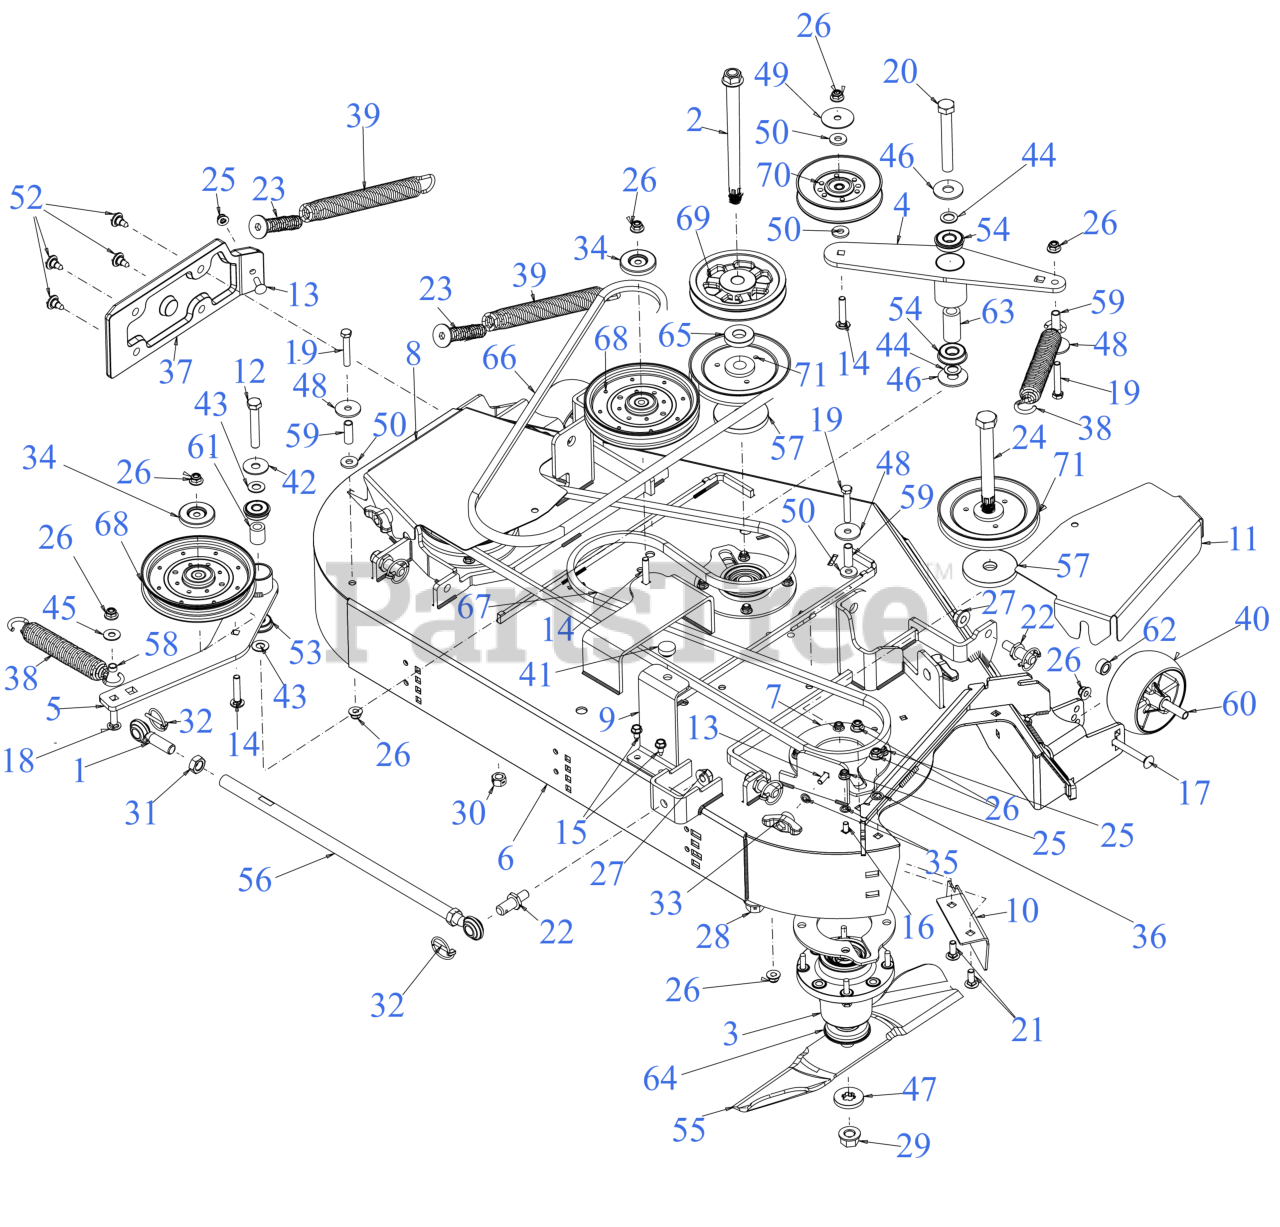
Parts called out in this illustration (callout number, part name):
1	MALE ROD END
2	SPINDLE SHAFT
3	SPINDLE ASSEMBLY
4	IDLER BRACKET
5	48" DECK IDLER BRACKET
6	48" FAB DECK
7	SPINDLE SUPPORT PLATE TOP & BOTTOM
8	BELT COVER (LH)
9	DECK STOP BRACKET
10	BAFFLE
11	48" BELT COVER (RH)
12	SCREW-HEX 1/2-13 x 3.00
13	CARRIAGE BOLT 5/16-18 x 1.00
14	CARRIAGE BOLT 3/8-16 x 2
15	SCREW 5/16-18 x .750
16	CARRIAGE BOLT 5/16-18 x .75
17	CARRIAGE BOLT 3/8-16 x 4.00 GR5
18	CARRIAGE BOLT 3/8-16 X1.25 GR5
19	SCREW 3/8-16 x 2.25 GR5
20	SCREW 5/8-18X4.5 GR5
21	CARRIAGE BOLT 3/8-16 x 1.00 GR5
23	SPRING INSERT SCREW
24	SPINDLE SHAFT
25	FLANGE LOCK NUT 5/16-18
29	FLANGE NUT - 5/8-18 GDE 8
30	HEX NUT CTR LK 1/2-13
31	HEX JAM NUT 5/8-18
32	LYNCH PIN .1875
33	WING KNOB 5/16-18
34	PULLEY CAP
35	PUSH NUT
36	PUSH NUT
37	DECK SKID PLATE (LH)
38	SPRING 1.25" DIA x 8.5" LONG
39	EXTENTION SPRING 1.20 x 11.35
40	DECK WHEEL
40	WHEELS-DELUXE 5"
41	RUBBER BUMPER 1.000 x .313
42	WASHER .51 x 1.5 x .07
43	FLAT WASHER .510 x .995
44	FLAT WASHER
45	WASHER-.395 x 1.0 x .62
46	FLAT WASHER 0.635xX1.755x0.110
47	FLAT WASHER - SPECIAL
48	FLAT WASHER .406X1.500X.105
49	HUB CAP WASHER .406 x 1.92 x .060
50	FLAT WASHER .406ID X1.0 OD
52	SHOULDER SCREW .43X.29X5/16-18 TT
53	ROLLER BEARING .5X1.37X.44
54	BALL BEARING W/RET
55	17" BLADE
56	TUBE .565 X .750 X 18.75"LG
57	DECK SPINDLE SPACER
58	SPACER
59	SPACER
60	SPACER .38X.49X3.05LG
61	SPACER 0.51 x 0.88 x 1.00
62	SPACER-.505 1D
63	SPACER 0.63 x 1.00 x 2.01
64	SPACER 0.790 x 2.75 x 0.486
65	SPACER
66	BELT B SEC x 87.30
67	BELT B SEC X 109.9
68	IDLER PULLEY
69	DRIVE PULLEY
70	IDLER PULLEY 5.06 OD
71	V-PULLEY 6.426"
